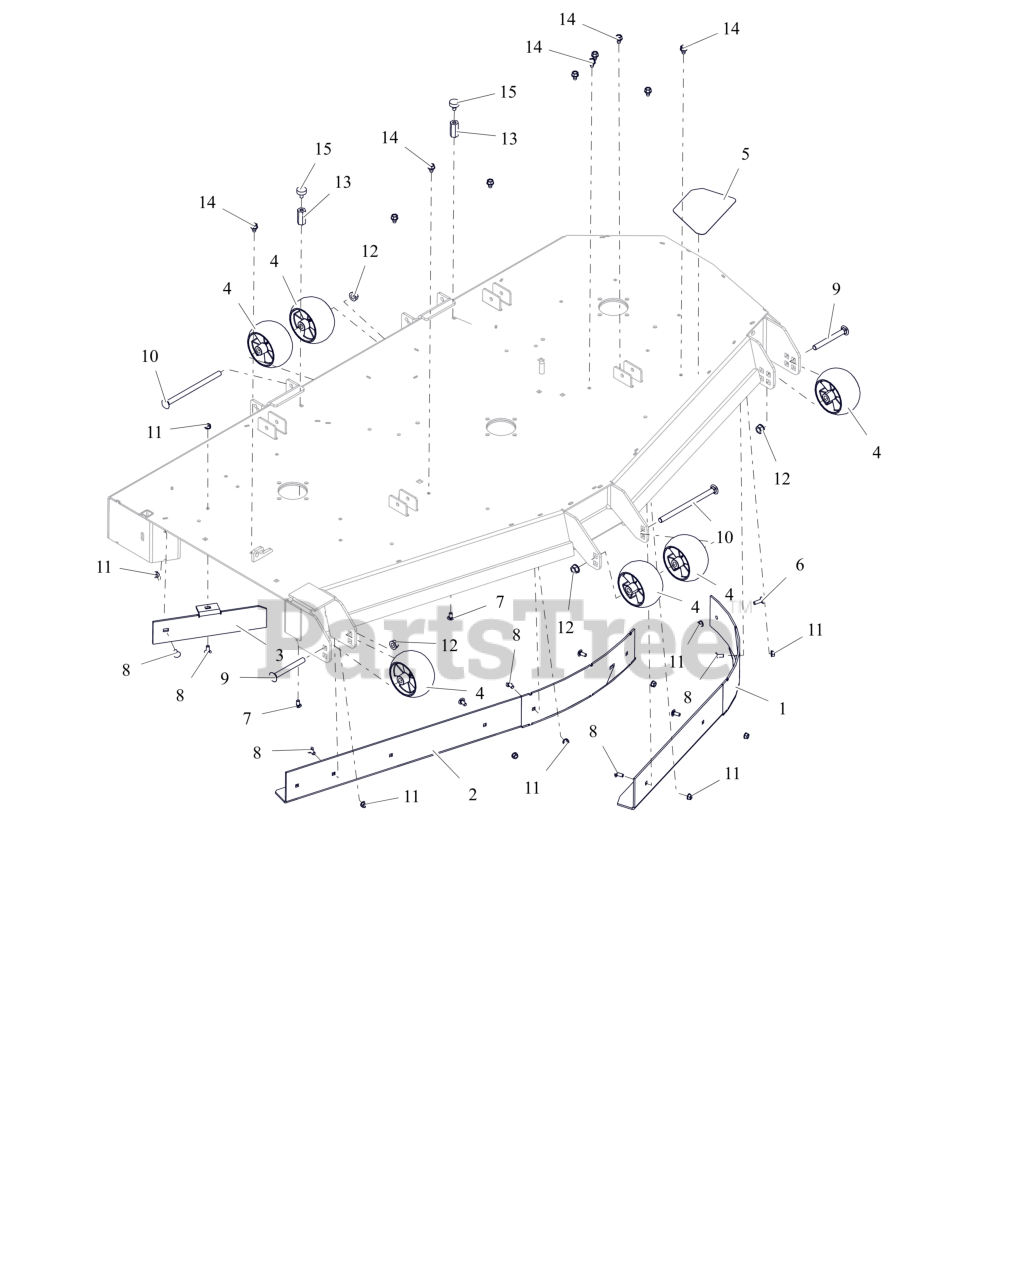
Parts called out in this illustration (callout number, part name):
1	WLDMT, 72" LH VACUUM BAFFLE (RED)
2	WLDMT, VACUUM BAFFLE 72" RH (RED)
3	72" DISCHARGE BAFFLE - RED
4	WHEEL, ANTI SCALP - 5X3 CTR W/RIBS
5	GRIP, STEP ANTI SKID
6	BLT,RHSSN .31-18X1.00 G5 ZCC
7	BTL,RHSSN .313-18 X 0.625 G5 ZCC
8	BLT, RHSSN.31-18X.750 G5 ZCC
9	BLT,RHNS .50-13X4.50 G5 ZCC NS
10	BLT,RHSN .50-13X8.00 G5 ZCC NS
11	NUT,LK-CTR-FLG .31-18 GF ZCC
12	NUT-LK-CTR-FLG .500-13 GG ZCC
13	NUT, COUPLING .312-18 X 1.625
14	SCR,TAP .375-16X.50 HWH TR ZCC
15	BUMPER, RUBBER
